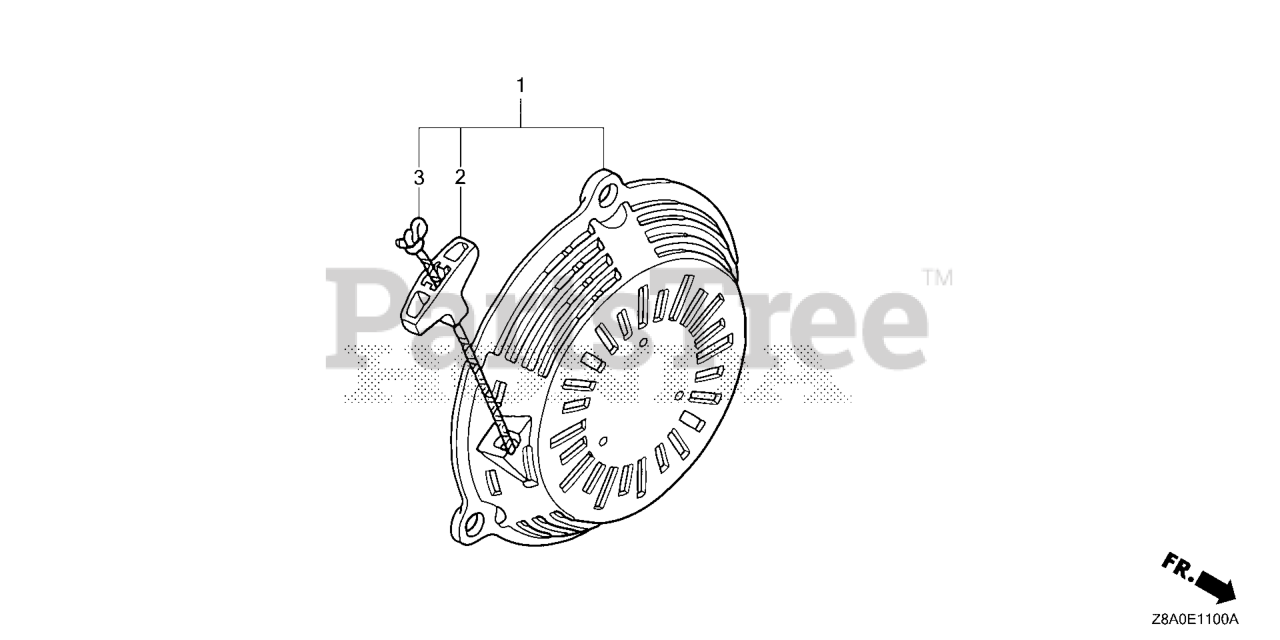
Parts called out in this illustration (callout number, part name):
1	STARTER ASSY., RECOIL *R280* (SHORT ROPE) (POWER RED)
1	STARTER ASSY., RECOIL *NH1* (SHORT ROPE) (BLACK)
2	KNOB, RECOIL STARTER
3	ROPE, RECOIL STARTER (#3.5X52")
